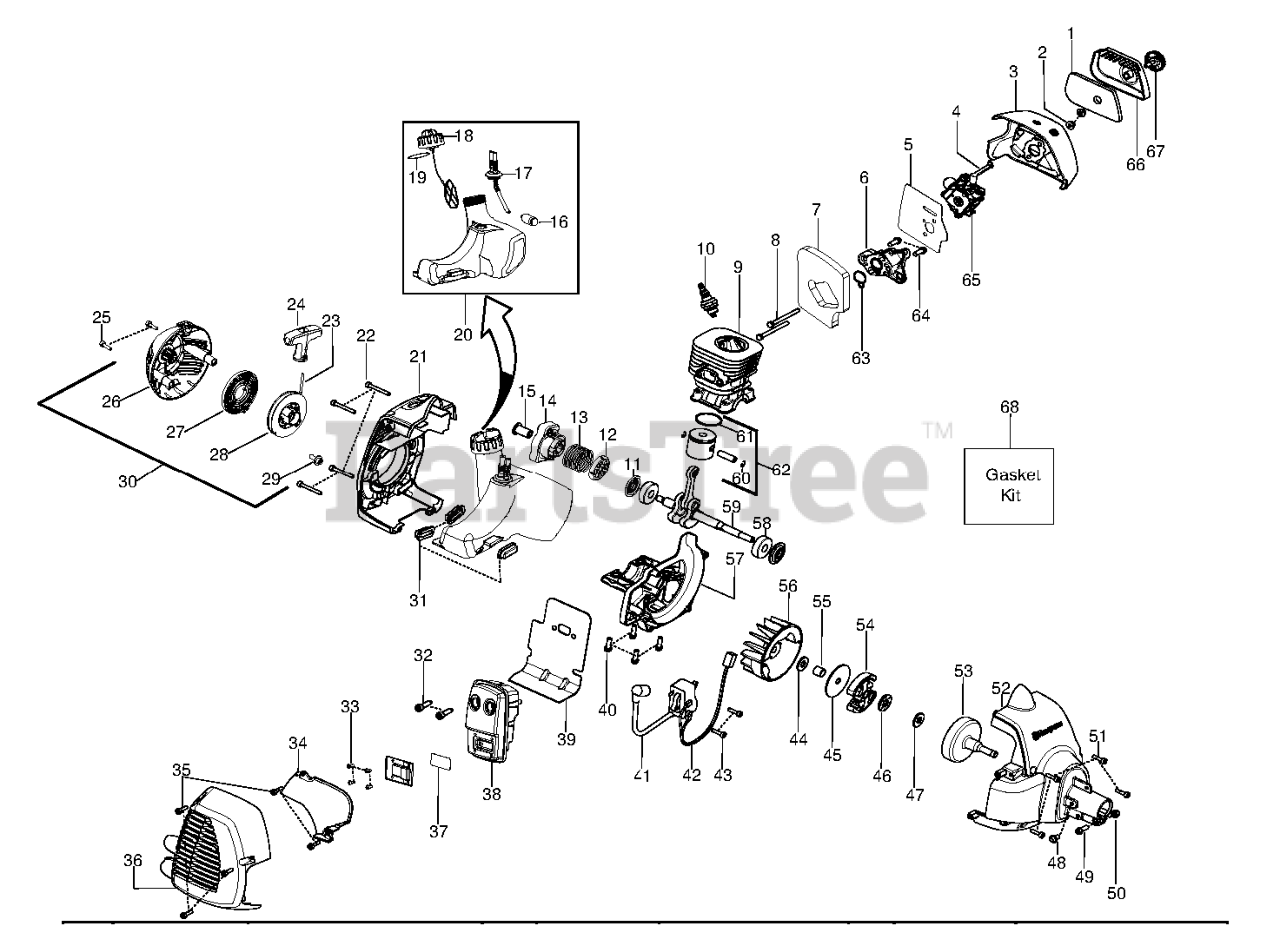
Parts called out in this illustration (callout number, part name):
1	THROTTLE CONTROL
1	THROTTLE CONTROL ASSY
2	STOP BUTTON
4	HANDLE
5	THROTTLE LOCK
7	VIBRATION DAMPER
8	HANDLE
9	RETURN SPRING
10	THROTTLE TRIGGER
11	VIBRATION ABSORBER
15	WIRING ASSY
16	SHORT CIRCUIT CABLE
17	THROTTLE CABLE
